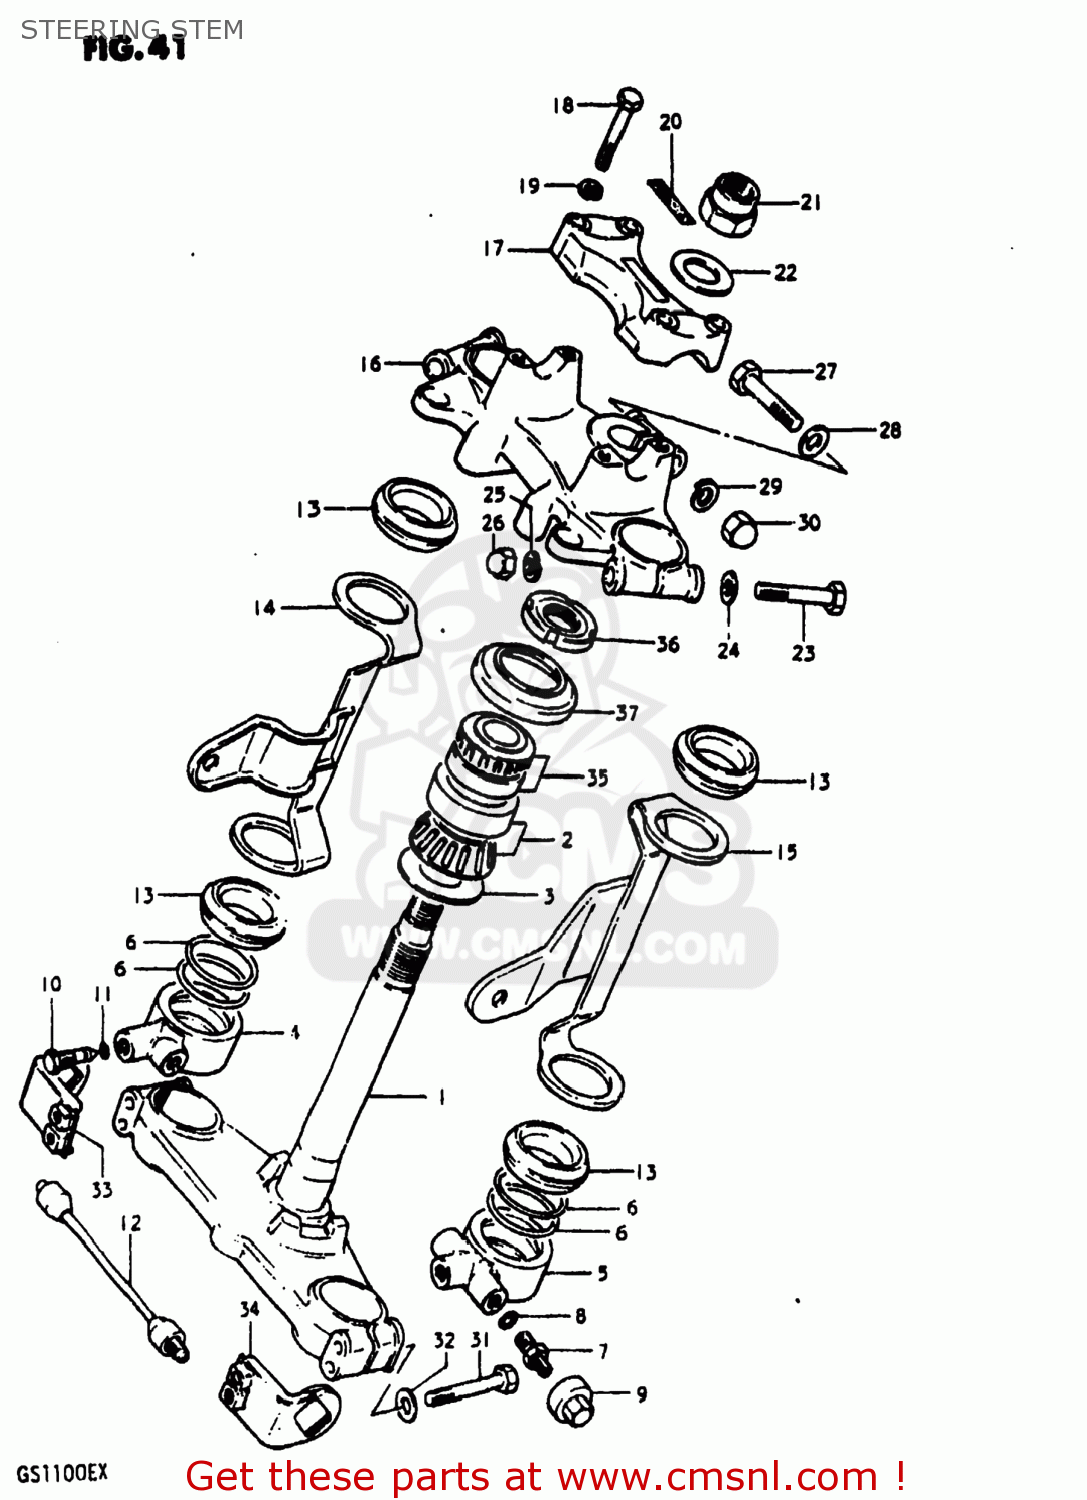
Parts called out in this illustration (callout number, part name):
1	STEM,STEERING
2	BEARING
3	WASHER,THRUST
4	JOINT,AIR,RIGHT
5	BRACKET,FORK CONNECTING
6	O RING
7	VALVE
8	O RING
9	CAP,VALVE
10	VALVE,STOP
11	O RING
12	HOSE
13	CUSHION,HEADLAMP BRACKET
14	BRACKET,HEAD L
15	BRACKET, HEAD LAMP LH
16	HEAD,STEERING STEM
17	HOLDER, HANDLE
18	BOLT
19	LOCK WASHER
20	EMBLEM,HANDLE CLAMP
21	NUT,FR FORK UPR BRACKET
22	WASHER
23	BOLT 10X55
24	WASHER
25	LOCK WASHER
26	NUT 10MM
27	BOLT 8X50
28	WASHER
29	WASHER,LOCK,8.
30	NUT,M8X1.25X12
31	BOLT 8X55
32	WASHER
33	BRACKET, TURN SIGNAL RH
34	BRACKET, TURN SIGNAL LH
35	TAPER,ROLLER BEARING
36	NUT,STEERING STEM(25X44X10)
37	DUST SEAL,STEERING,UPPER
